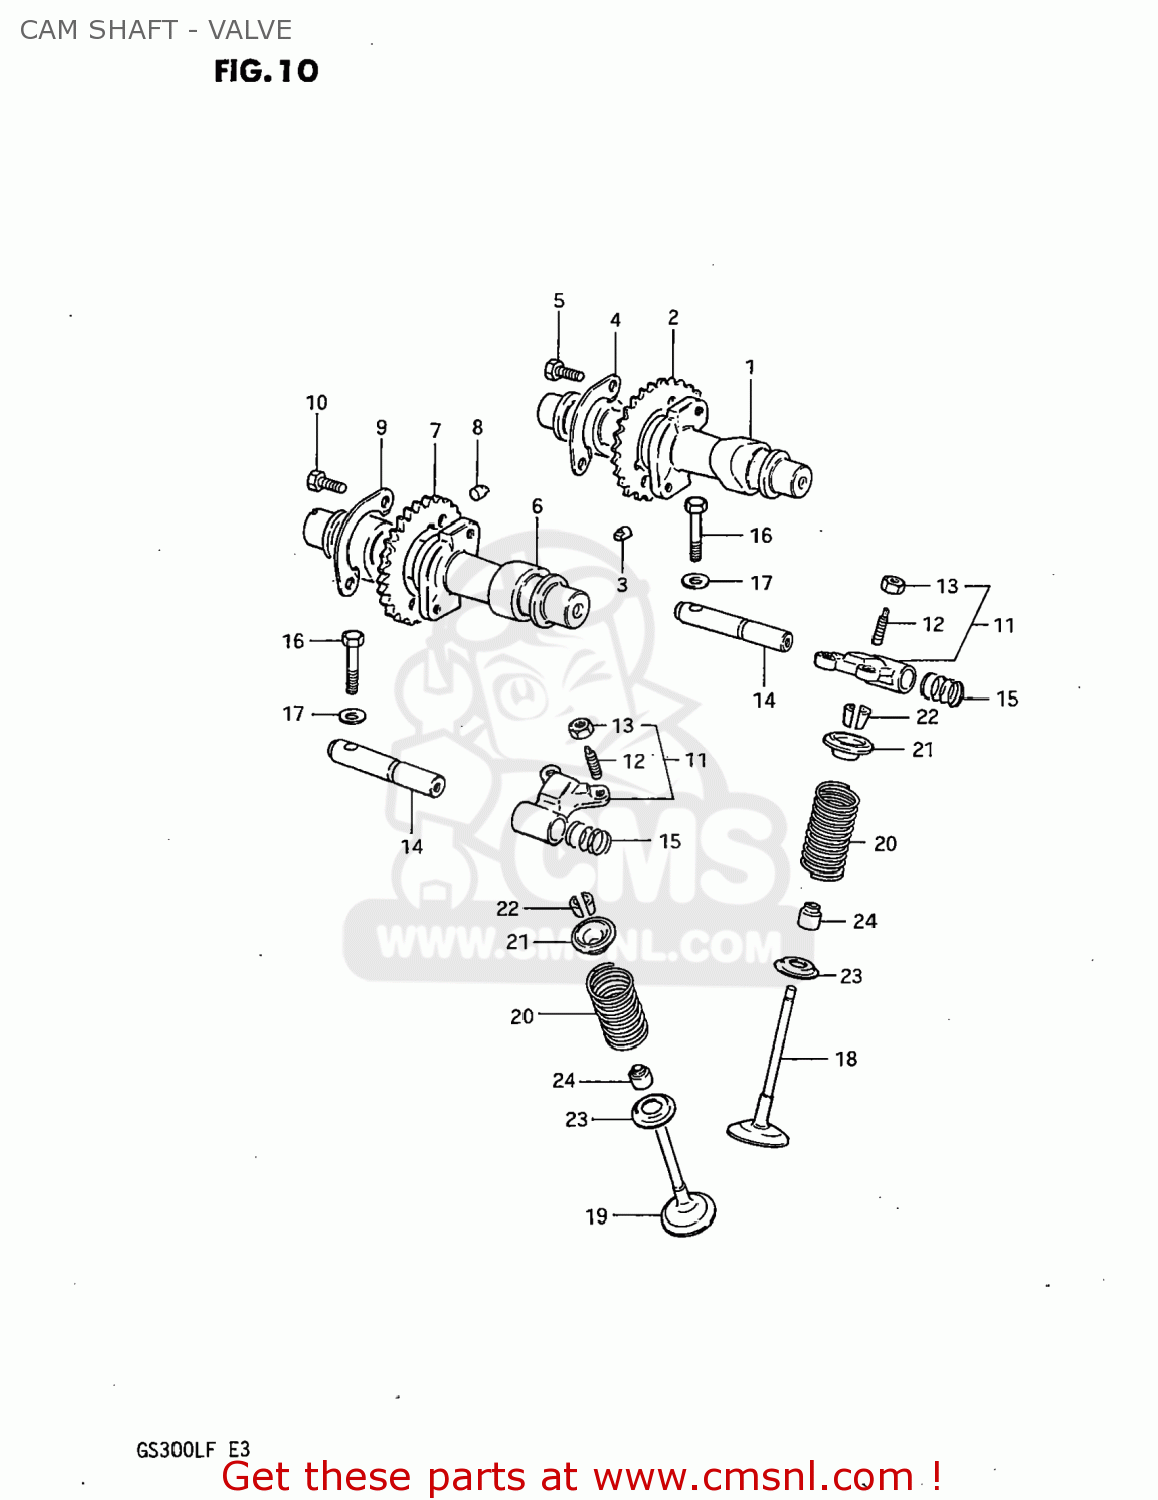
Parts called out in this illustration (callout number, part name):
1	CAMSHAFT
2	SPROCKET,INTAKE CAMSHAFT
3	PIN,SPROCKET
4	WASHER,CAM CHAIN SPROCKET
5	BOLT(6X12.5)
6	CAMSHAFT,EXHAUST
7	SPROCKET,EXHAUST CAMSHAFT
8	PIN,SPROCKET
9	WASHER,CAM CHAIN SPROCKET
10	BOLT(6X12.5)
11	ARM,VALVE ROCKER
12	SCREW,TAPPET ADJUSTING
13	NUT,ADJUSTING
14	SHAFT,VALVE ROCKER ARM
15	SPRING
16	BOLT
17	WASHER, LOWER
18	VALVE,INTAKE
19	VALVE,EXHAUST
20	SPRING,VALVE
21	RETAINER,VALVE SPRING
22	COTTER VALVE
23	SEAT,VALVE SPRING
24	OIL SEAL
